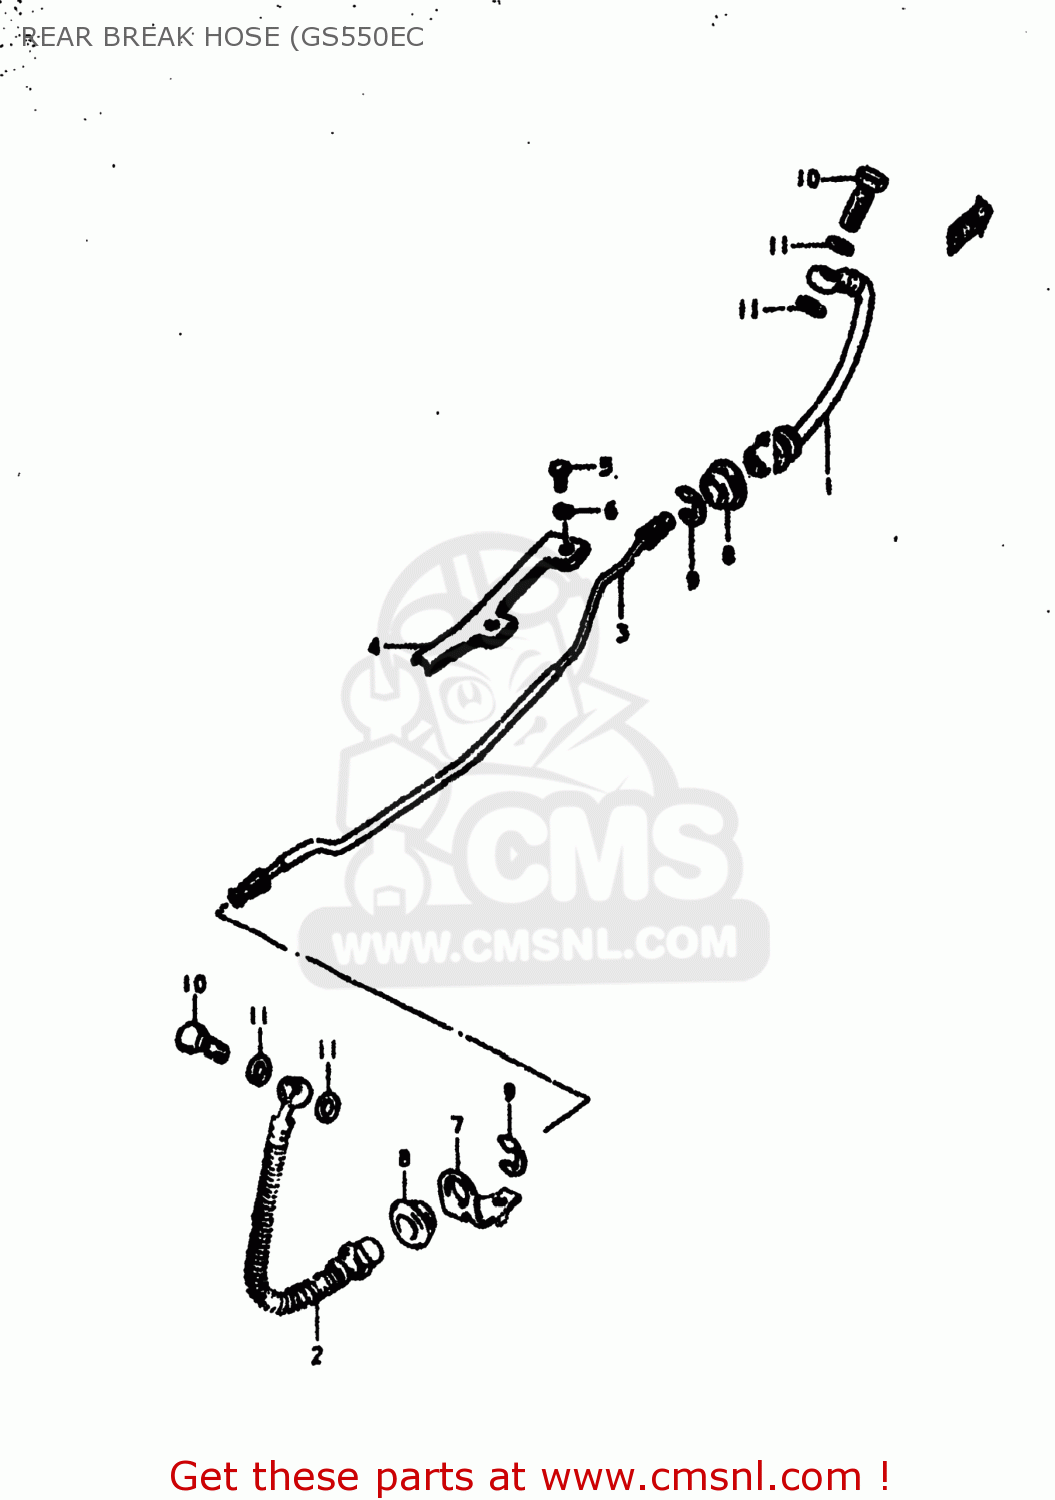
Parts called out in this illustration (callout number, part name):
1	HOSE,REAR BRAKE
2	HOSE,RR BRAKE NO.2
3	PIPE,REAR BRAKE
4	COVER,REAR BRAKE PIPE
5	BOLT(6X8)
6	LOCK WASHER
7	GUIDE,BRAKE HOSE
8	GROMMET,BRAKE HOSE GUIDE
9	E RING
10	BOLT UNION
11	WASHER
